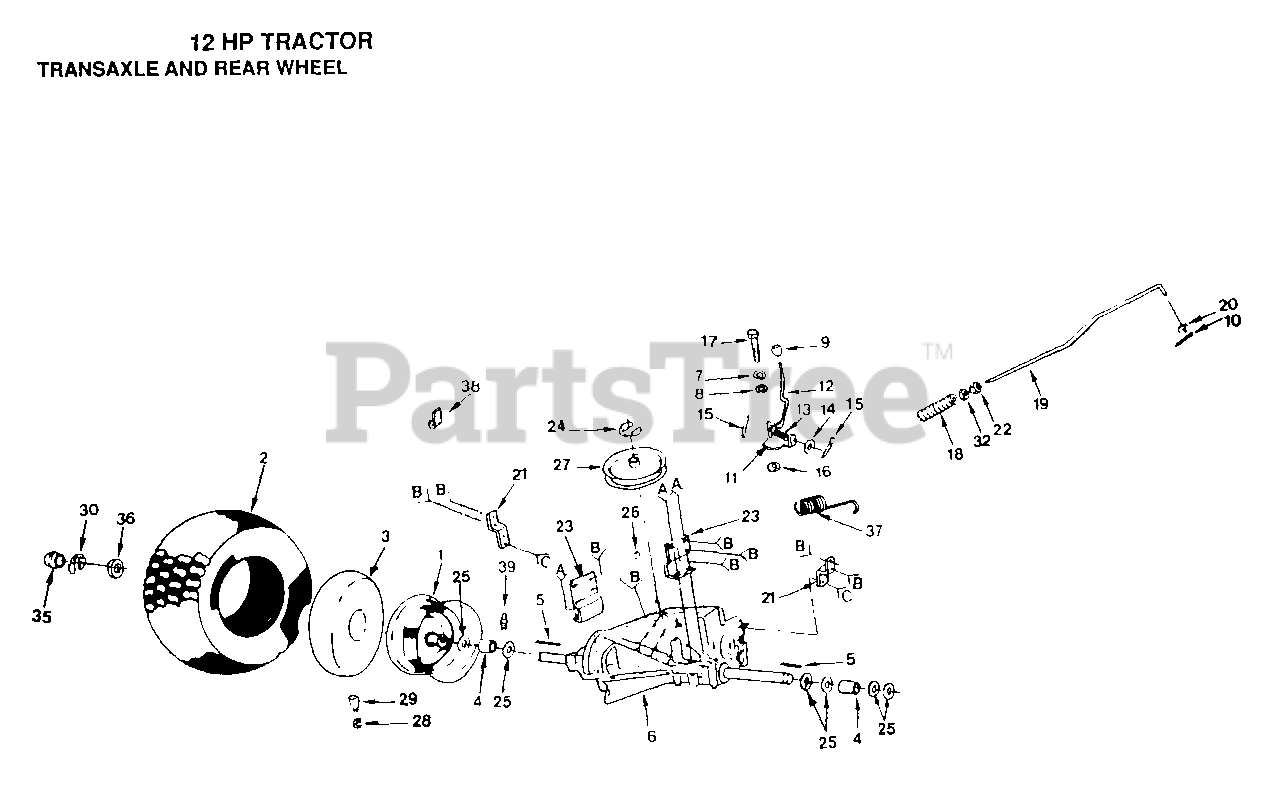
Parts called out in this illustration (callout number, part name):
3	TUBE.18X9.5-8
4	SPACER LT
5	SQUARE KEY
6	TRANSAXLE ASSY
7	LOCKWASHER
8	WASHER LT
9	KNOB.DUCKHEAD.1/2
10	COTTER PIN
11	PLATE SHIFT LT
12	ROD SHIFTER
13	SPRING LT
14	WASHER
15	PIN COTTER 1/8
16	"LINK, CLUTCH T"
18	SPRING ROD LT
19	BRAKE ROD LT
20	WASHER
21	STRAP TORQUE
22	NUT
23	BRACKET LT
25	WASHER
27	PULLEY TRANS
28	VALVE CAP
29	VALVE STEM LT
30	E-RING LT
35	HUB CAP
36	WASHER
38	CLIP T
39	FITTING LT
